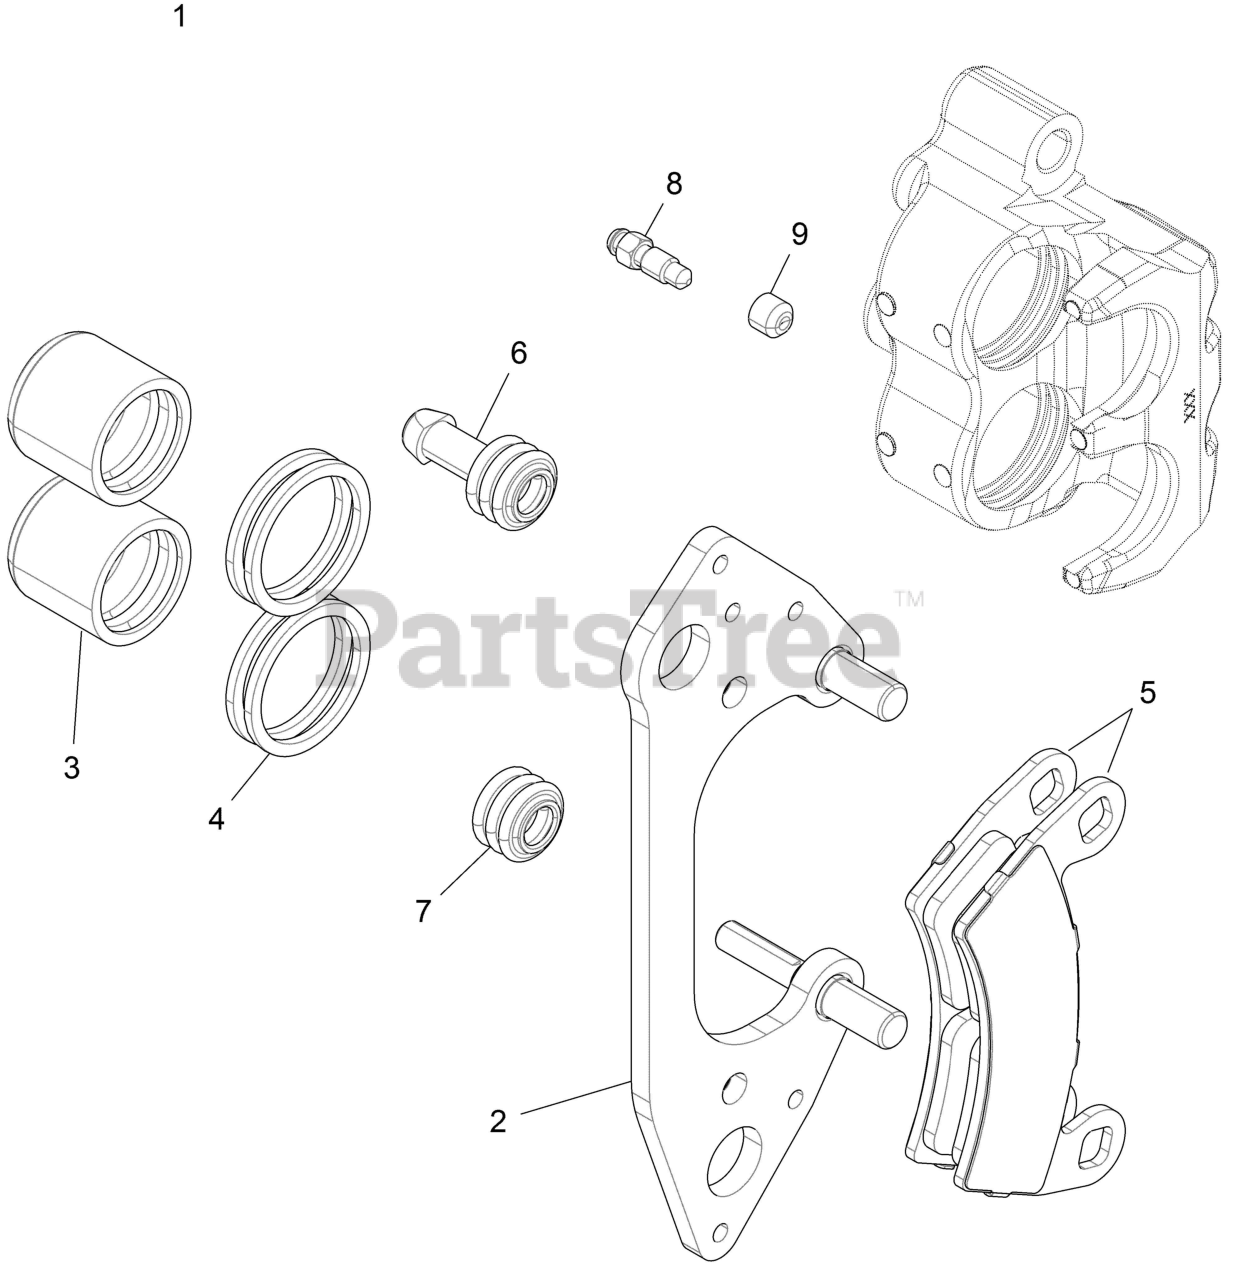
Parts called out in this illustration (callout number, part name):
1	ASM-BRK-CAL-L-DB1-3/8-GROOVED
1	ASM-BRK-CAL-R-DB1-3/8-GROOVED
2	ASM., CALIPER, MOUNT, FRONT
3	PISTON-BRAKE,1.375,AL,GROOVED
4	SEAL-CALIPER,INNER,1.375"
5	KIT, BRAKE PAD ASM.
6	BOOT-PIN BUSHING
7	BOOT-PIN SEAL
8	SCR-M7X1.0,BLEEDER,OLIVE D
9	SCR-M10X1.0X8,SOC SET-OD
